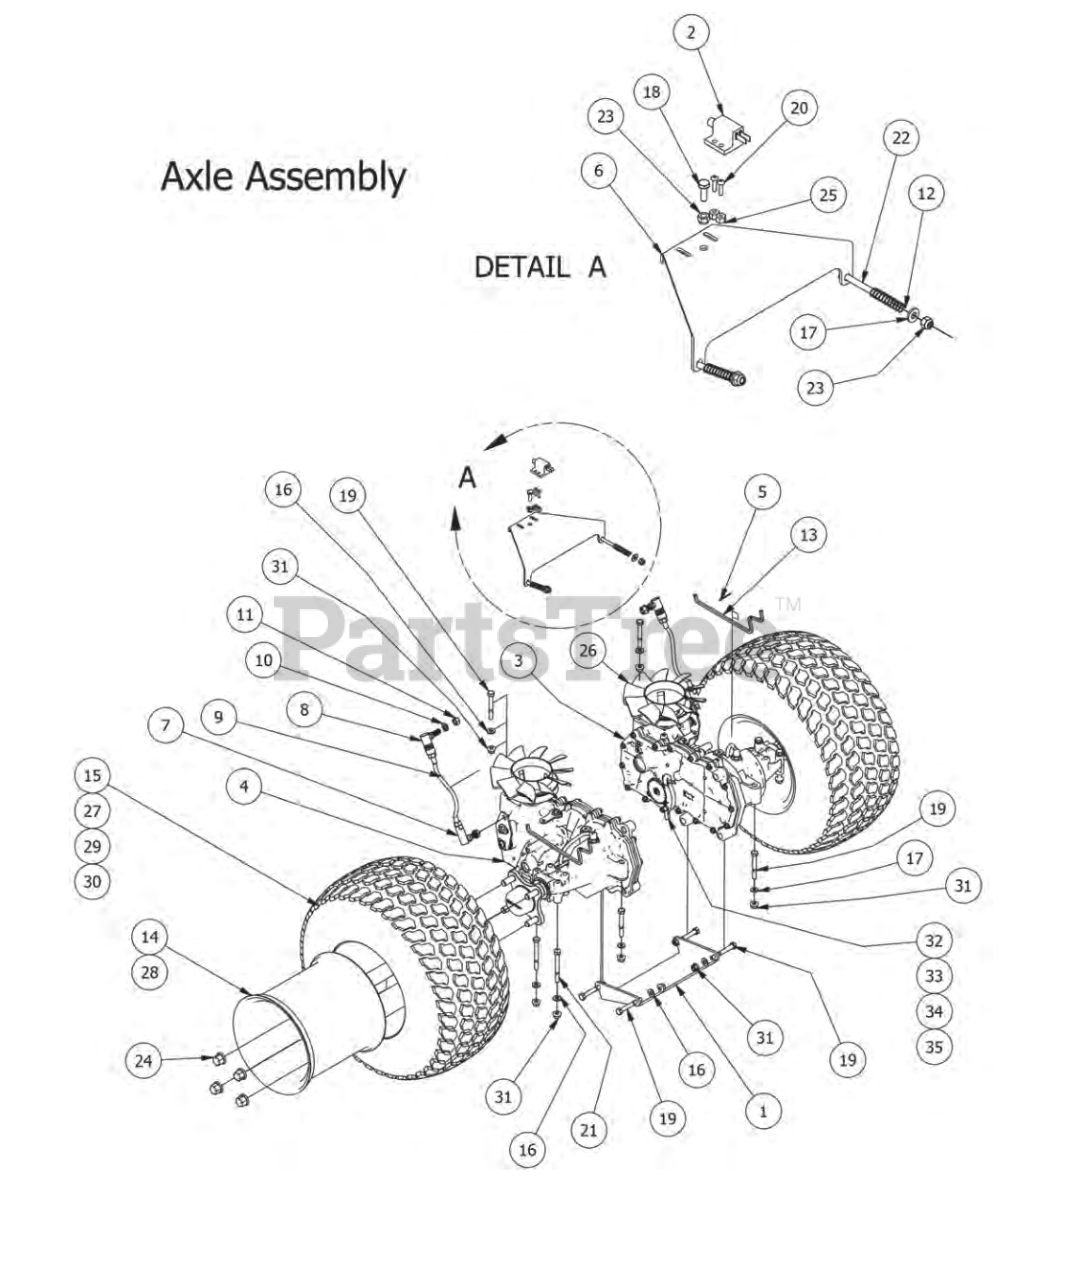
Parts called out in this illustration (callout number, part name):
1	MZ Transaxle Support (Lower)
2	Safety Switch
3	EZT-Right MZ Models
4	EZT- Left MZ Models
5	Cotter Pin-Brake bar on Mz
6	MZ Brake Lock Bracket
7	3/8-24 Ball Joint
8	Quick Release Ball Joint
9	MZ/Magnum Push Rod - 2014
10	3/8" Lock Washer
11	3/8" Fine Threaded Jam Nut
12	Brake Spring
13	MZ Brake Release Bar
14	Rear rim for a 48 & 54"
15	18 x 9.50-8 Tire Only MZ 48 &54" Deck only
16	5/16" Flat Washer
17	1/4" Flat Washer
18	1/4" x 3/4" Hex Bolt
19	5/16" x 2 1/2" Bolt
20	10-24 X 5/8 BS C/S 18-8 SS
21	5/16" x 3" Hex Bolt
22	1/4-20 x2-1/2 Gr2 hex C/s zinc
23	1/4" Nylock Nut
24	Acorn Lug Nut
25	10-24 Nylon Insert Locknut
26	MZ Fan & Pulley Kit
27	42" MZ 18x 7.50-8 tire only
28	Rear rim only 42" MZ
29	18x9.50-8 48 & 54" Deck Tire and Wheel Assembly
30	18x8.50-8/8" 42" Deck Tire and Wheel Assembly
31	5/16" Nylon Flange Nut
32	MZ Brake Cog Kit
33	MZ Retainer Ring for Brake
34	MZ Brake Gear
35	MZ Brake Arm Kit
